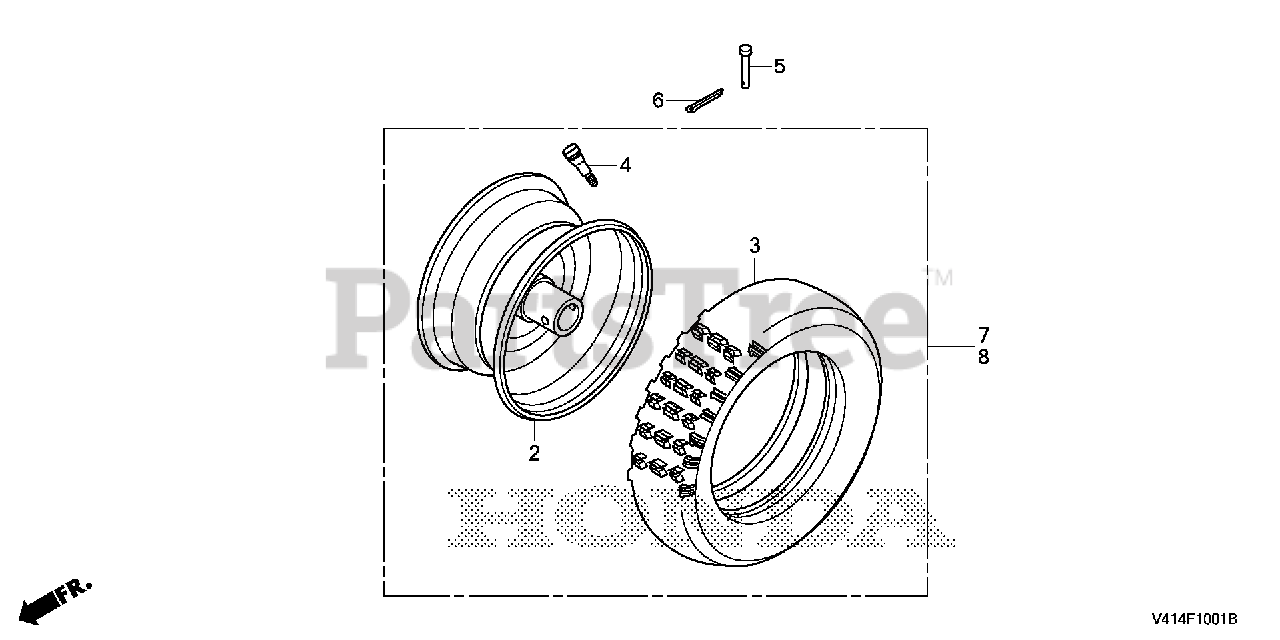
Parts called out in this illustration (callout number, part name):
3	TIRE (15X5.00-6)
4	VALVE, RIM
5	PIN, CLEVIS (6.3X35)
6	PIN, SPLIT (3.0X18)
7	WHEEL ASSY., R. (15X5.00-6)
8	WHEEL ASSY., L. (15X5.00-6)
